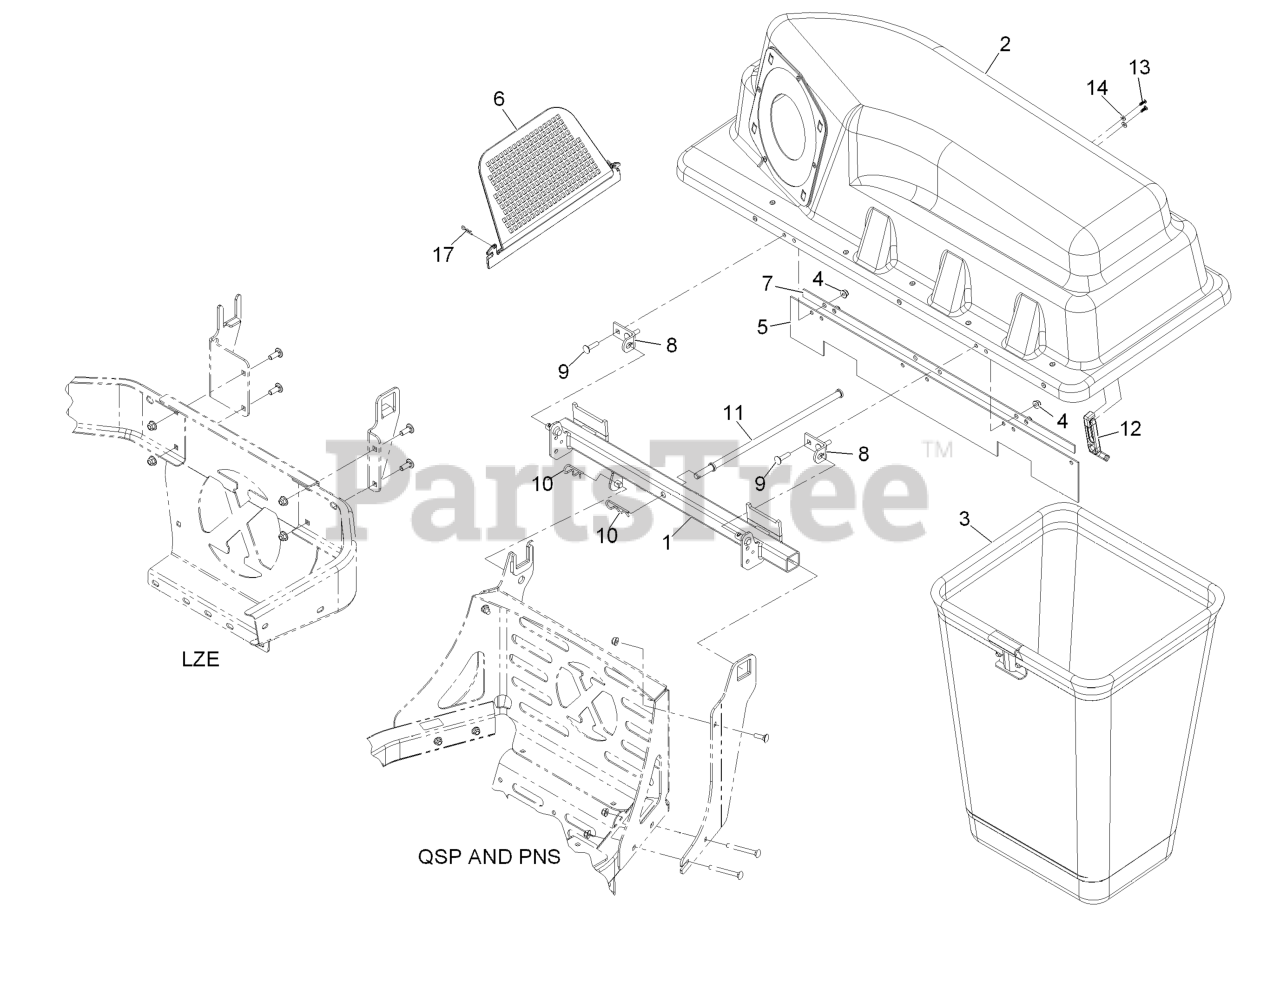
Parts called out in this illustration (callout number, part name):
1	FRAME PIVOT ASM
2	BAGGER HOOD ASM
3	BAG AND FRAME ASM
4	NUT-HF, NI
6	SCREEN-BAGGER
7	PLATE-BACKING
8	BRACKET-PIVOT, HOPPER
9	Bolt-Carriage 5/16-18 X 1 1/4
10	PIN-HAIR
12	LATCH-RUBBER
13	SCREW-PLASTITE
14	WASHER-FLAT
